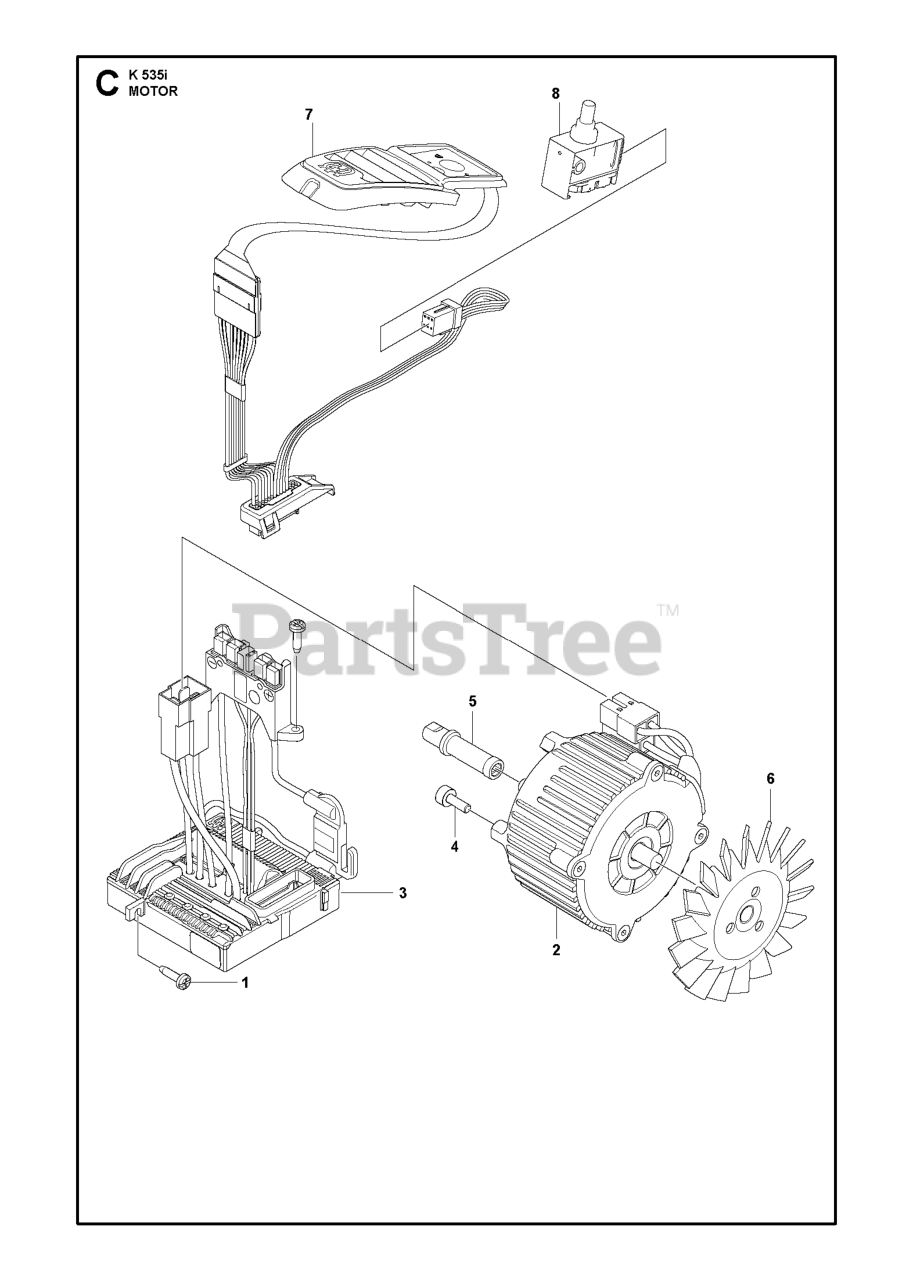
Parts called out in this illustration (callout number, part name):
1	SCREW ITXPANT WN 1452 3.5X12 T
2	MOTOR ASSY BLDC D70
4	SCREW ITXSCM M4X15 T27 12.9 T
7	WIRING ASSY SIGNAL BATTERY CUT
8	TRIGGER SWITCH IPX4
